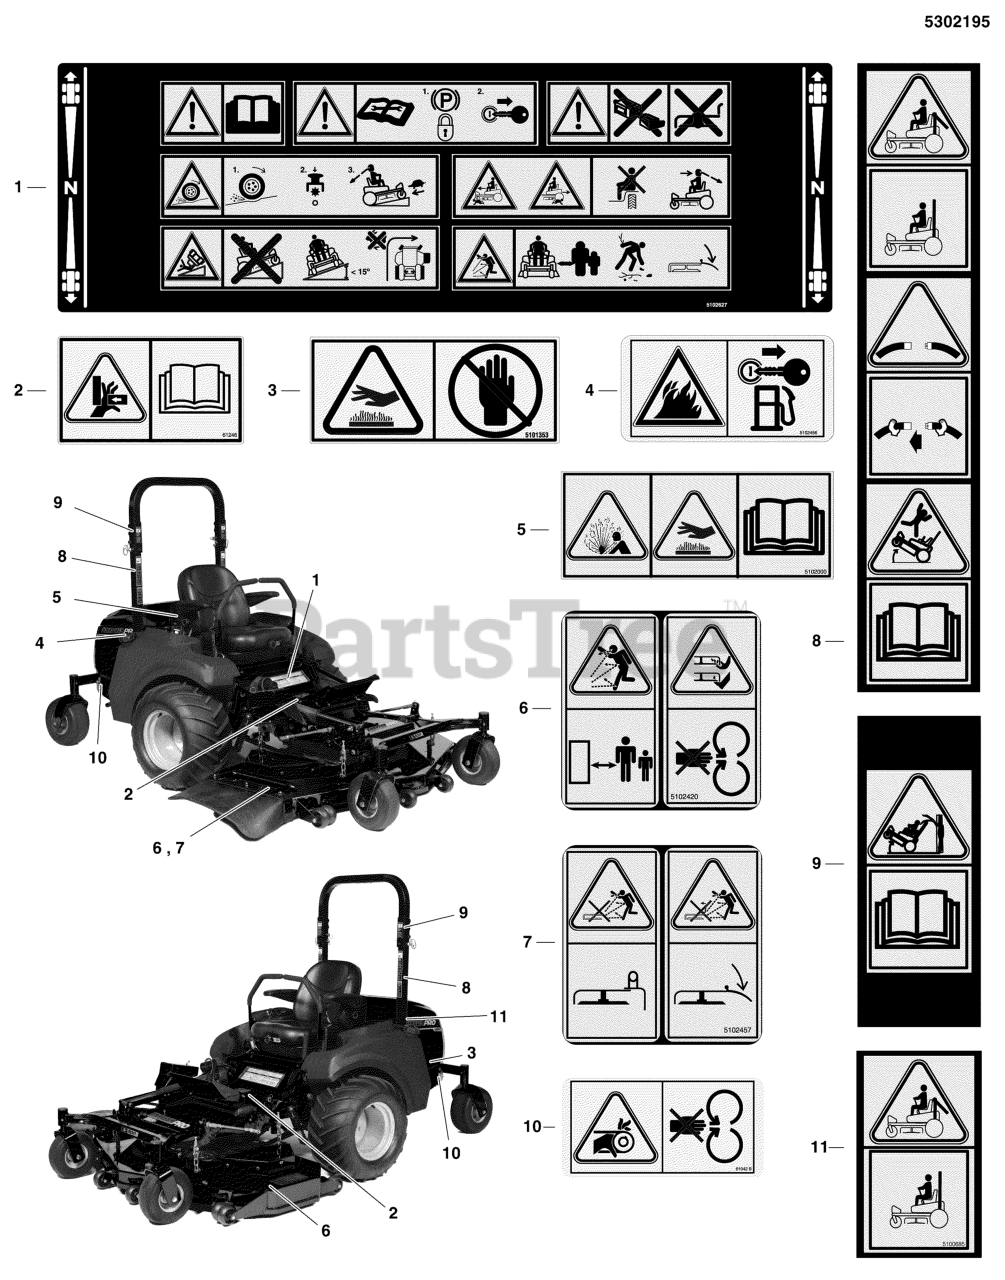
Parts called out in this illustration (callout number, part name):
1	DECAL, MAIN SAFETY, ANSI CE
2	DECAL, PINCH POINT, CE
3	DECAL, HAND IN FLAME
4	DECAL, FIRE ANSI EXPORT
5	DECAL, WARNING, HOT
6	DECAL, DANGER, MOWER DECK, ANSI EXP
7	DECAL, DANGER DISCHARGE ANSI EXPORT
8	DECAL, SAFETY, CE ROPS
9	DECAL, SAFTY, CE ROPS, OBS
10	DECAL, CE DANGER
11	DECAL, WARNING, ROLL BAR, CE
